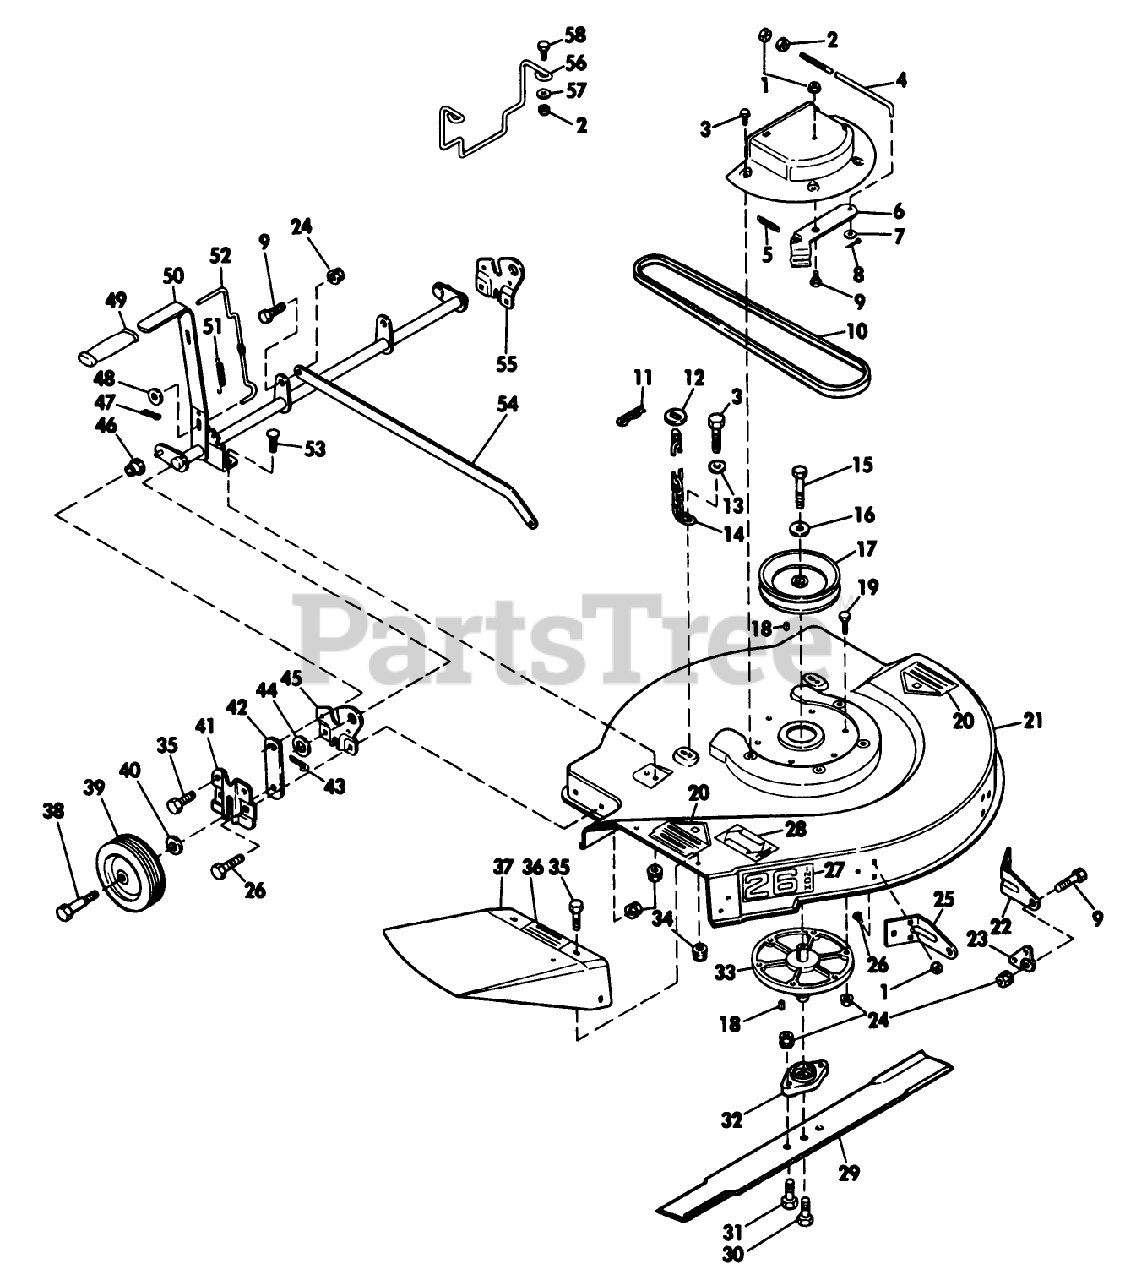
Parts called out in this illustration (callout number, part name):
1	NUT
2	Nut-Jam-Blade Brake Rod
3	Screw-Belt Cover
4	Rod-Blade Brake
5	Spring-Blade Brake
6	Lever-Blade Brake
9	Screw
10	V-Belt Mower Drive
11	Clip-Hairpin
12	Washer
13	WASHER
14	Chain
15	Screw-Nylok
16	Washer
17	Blade Pulley Assembly
18	Key-Bld-Spindle
19	Screw-Spindle Assembly
20	Decal-Caution Pan
21	Housing-Blade
22	Bracket-Blade Housing-L.H.
23	Pivot-Blade Housing
24	Nut
25	Bracket-Blade Housing R.H.
26	Bolt
27	Decal-26 Inch
28	Decal-Blade Positions
29	Blade
30	Screw-Blade
31	Screw-Blade
32	Adapter-Blade
33	Spindle Assembly
34	STOP NUT
36	Decal-Caution
37	Deflector
38	Screw
39	Wheel Tire Assembly
41	Retainer-Height Adj. Slide
42	Slide-Height Adjuster
43	Cotter Pin
44	Washer-Height Adjuster
45	Bracket-Wheel Mounting R.H.
46	Bushing-Height Adjuster
47	Pin
48	WASHER
49	Grip-Handle
50	Shaft Assembly-Height Adjustment
51	Spring-Latch
52	Latch-Slide
54	Bar-Parallel
55	Bracket-Wheel Mounting L.H.
56	Retainer-Blade Belt
